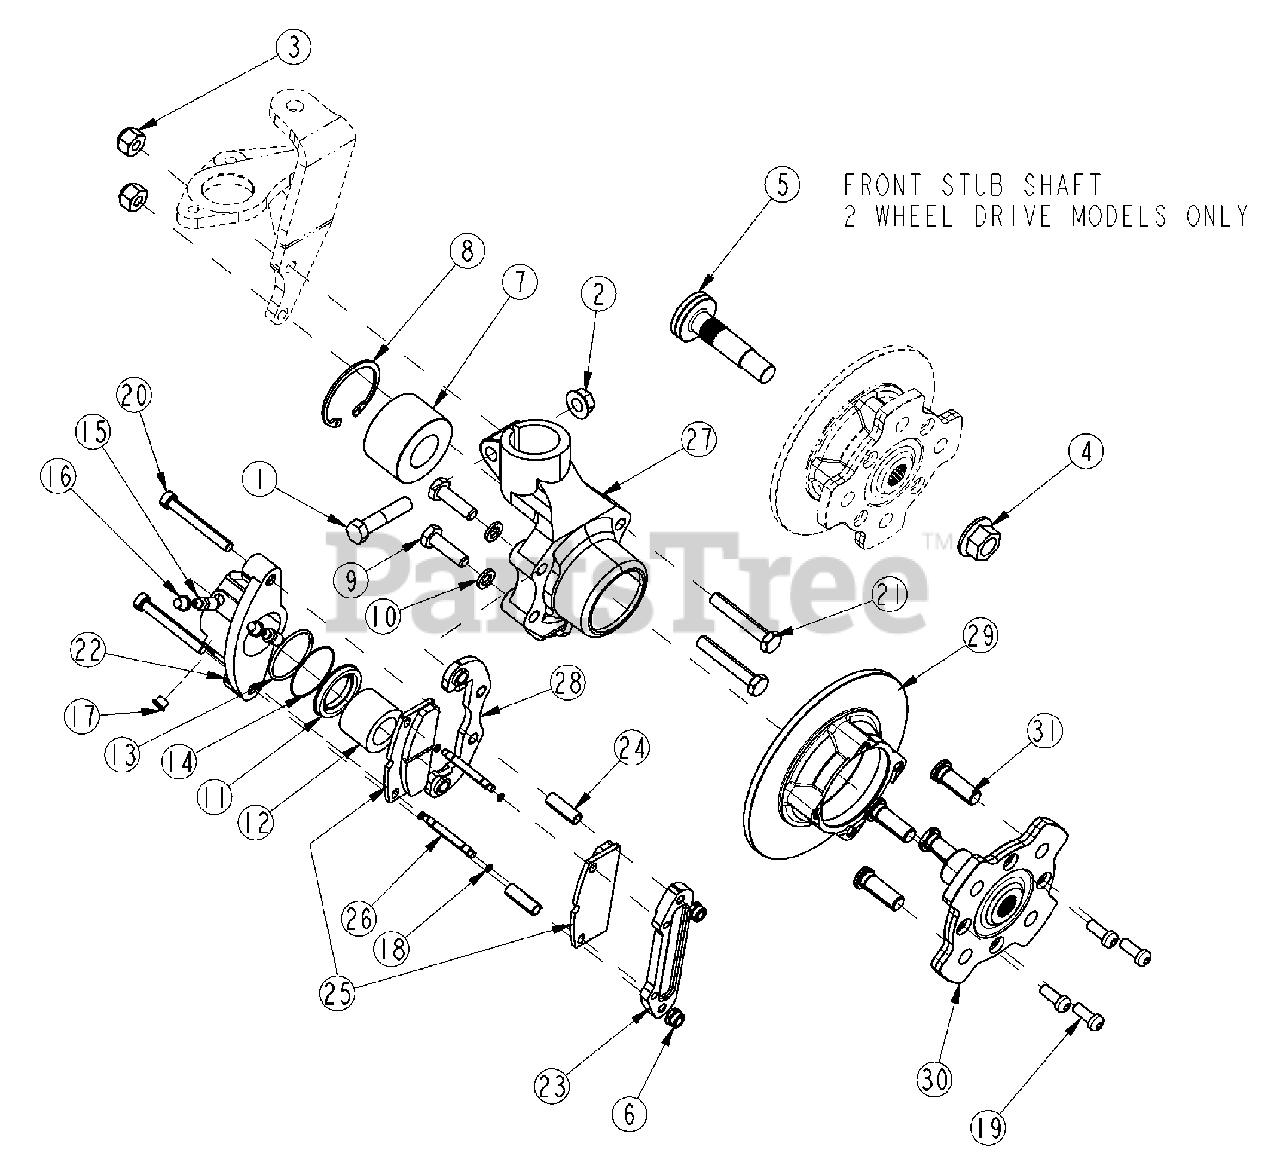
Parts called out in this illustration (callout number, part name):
1	HHCS 7/16-14X2 GR5
2	NUT HEX FLANGE LOC 7/16-14 PLT
3	NUT HEX NYLOCK M10X1.5 PLT
4	NUT HEX M16X1.5 TOP LOCK PLT
5	FRNT DISC BRAKE STUB SHAFT 2WD
6	NUT M8
7	BALL BEARING 60,05X30X37
8	SNAP RING
9	SCREW M 10 X 1.25 X 35
10	M 10 WASHER
11	DUST BOOT RING
12	CAP
13	SEALING RING
14	RUBBER DUST BOOT
15	BLEEDER SCREW
16	BOOT
17	PLUG
18	ELASTIC RING
19	SCREW M8 X 20
20	SCREW M8 X 65
21	HHS M10X1.5X50 PLT
22	CALIPER BODY
23	REACTION BRACKET
24	SPACER
25	BRAKE PAD KIT (COMP. 2 WHEELS)
26	PIN
27	WHEEL PIVOT Rev. 2
28	CALIPER CLAMPING PLATE
29	DISC BRAKE
30	CMEX FLANGE WITH STUDS Rev. 2
31	RPBY F181 Rev. 1
32	STUD
